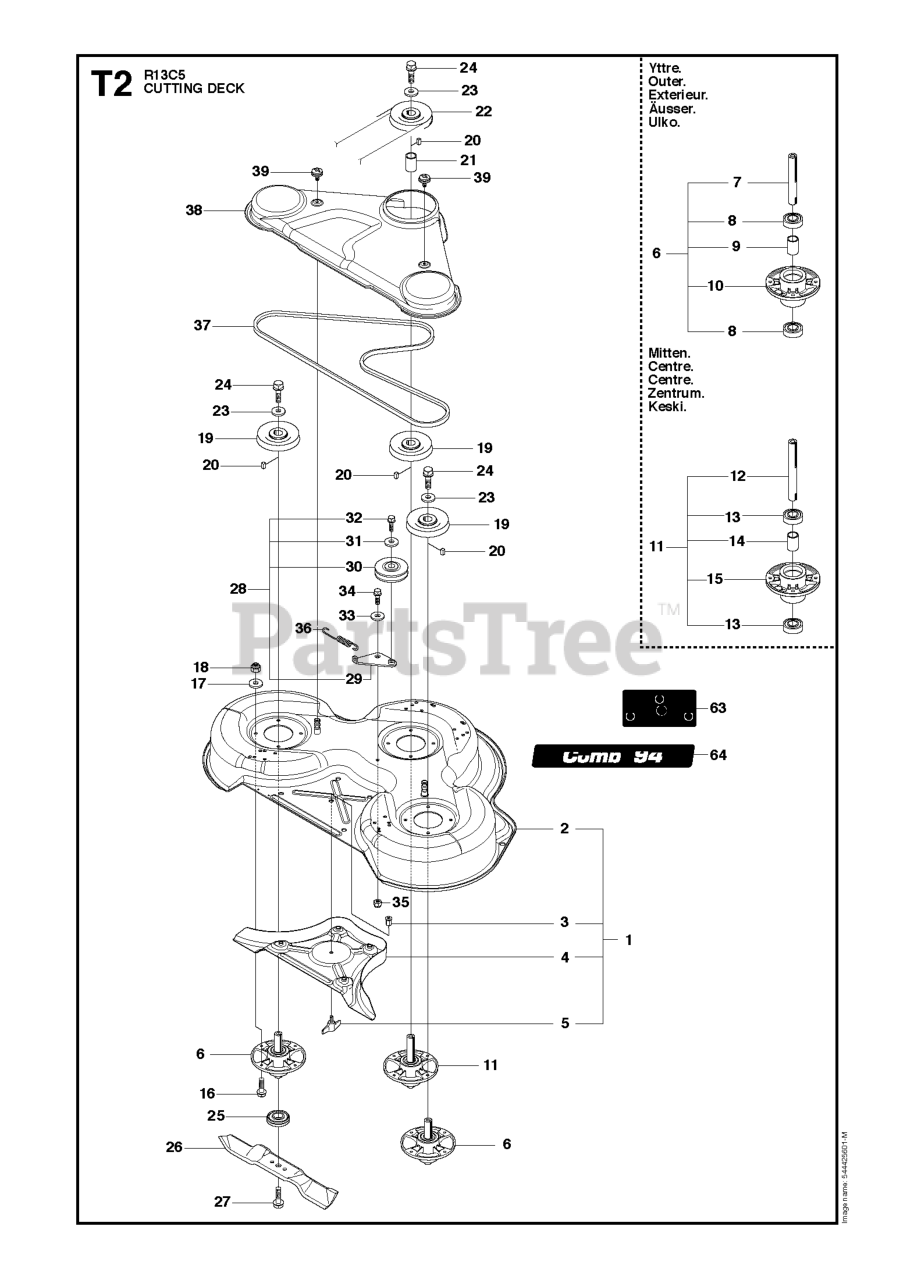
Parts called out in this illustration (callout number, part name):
4	PLUG C93 & C94
6	RP SPINDLE ASSY
10	BEARING HOUSING
15	BEARING HOUSING
17	WASHER BRB 8.4X17
18	LOCKNUT M8
21	SPACING SLEEVE
26	BLADE
30	PULLEY
33	WASHER
35	LOCKNUT M8
